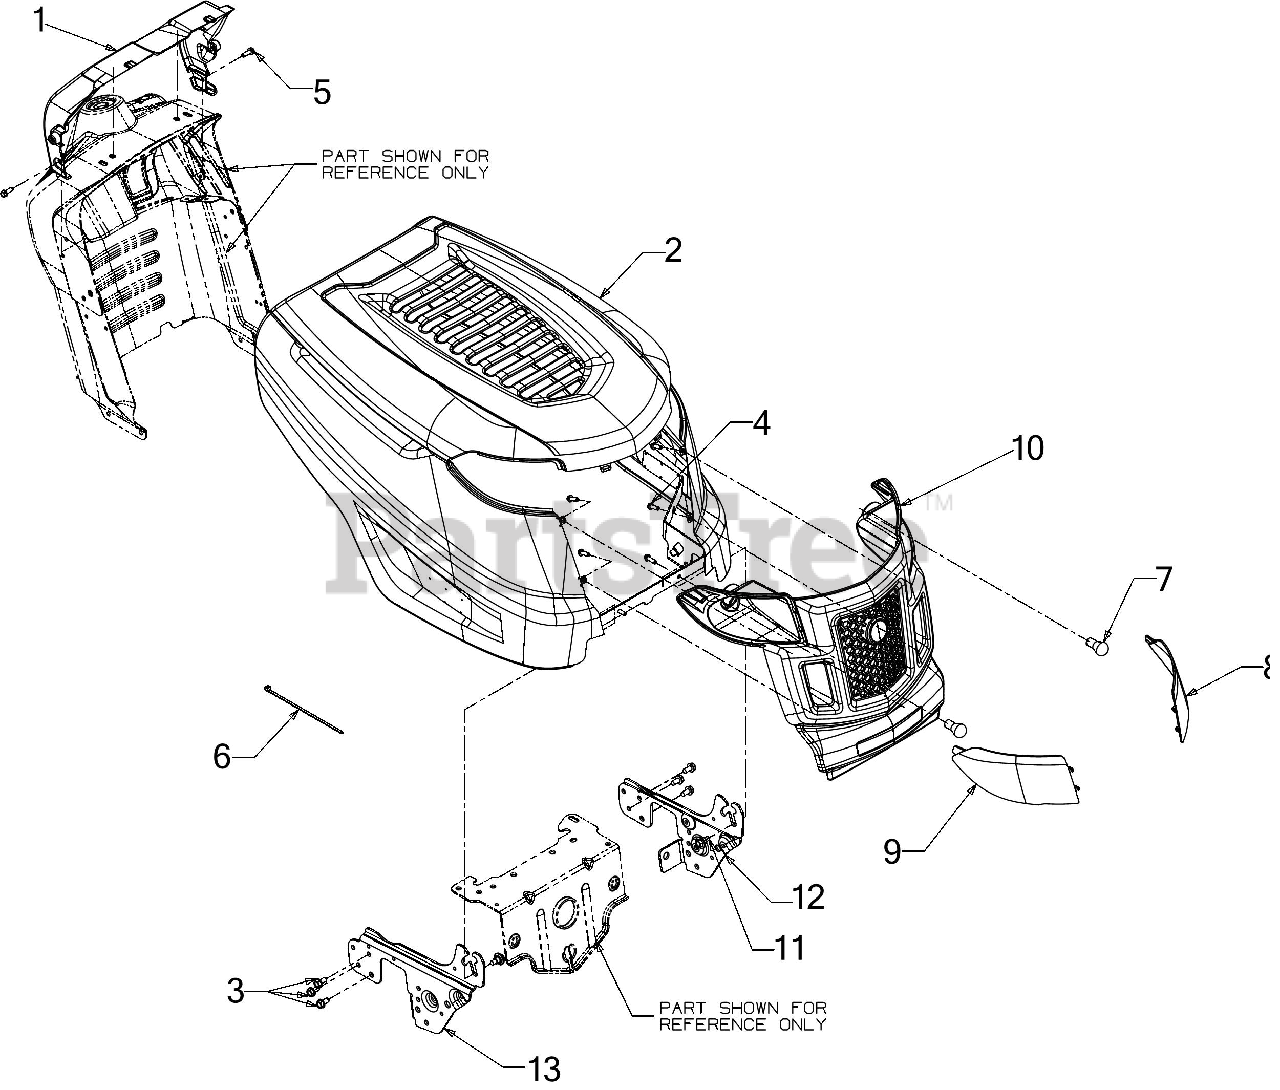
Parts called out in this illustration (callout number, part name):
1	DASH COLLAR
2	HOOD ASSEMBLY (K STYLE)
3	SCREW 5/16-18 x .750
4	SCREW 1/4 x .750
5	SCREW 1/4-15 x .750
6	7" CABLE TIE
7	MINIATUURE BULB 12V
8	LENS (LH)
9	LENS (RH)
10	GRILLE (K STYLE)
11	SHOULDER SCREW .43X.29X5/16-18 TT
12	SUPPORT BRACKET (LH)
13	SUPPORT BRACKET (RH)
